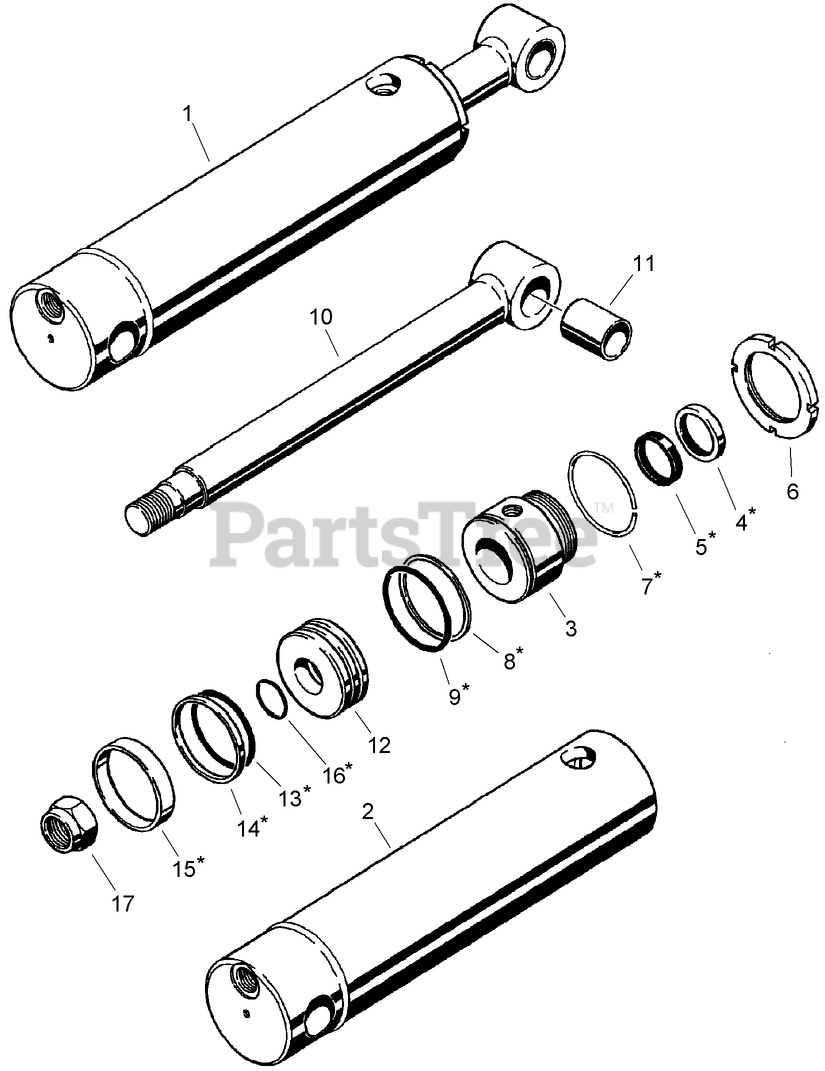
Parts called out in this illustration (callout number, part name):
1	CYLINDER ASSEMBLY - 76 (3) ID x 203 mm (8 inch) Stroke, Plow Lift
2	TUBE - Cylinder
3	GLAND - Cylinder
4	WIPER - Piston Rod
5	SEAL - Rod
6	NUT - Gland Locking
7	RING - Retaining, Gland
8	RING - Backup, Outer
9	O-RING - 2-3/4 ID x 1/8 inch Wide, Gland, Outer
10	ROD - Piston
11	BUSHING - Piston Rod, Rod Eye
12	PISTON - Cylinder
13	O-RING - 2-5/8 ID x 1/8 inch Wide, Piston Seal, Outer
14	SEAL - Piston, Piston, Outer
15	RING - Wear, Piston
16	O-RING - 1-1/2 ID x 1/8 inch Wide, Piston Seal, Inner
17	NUT - Hex, Self-Locking, 1-1/8 - 12 inch
